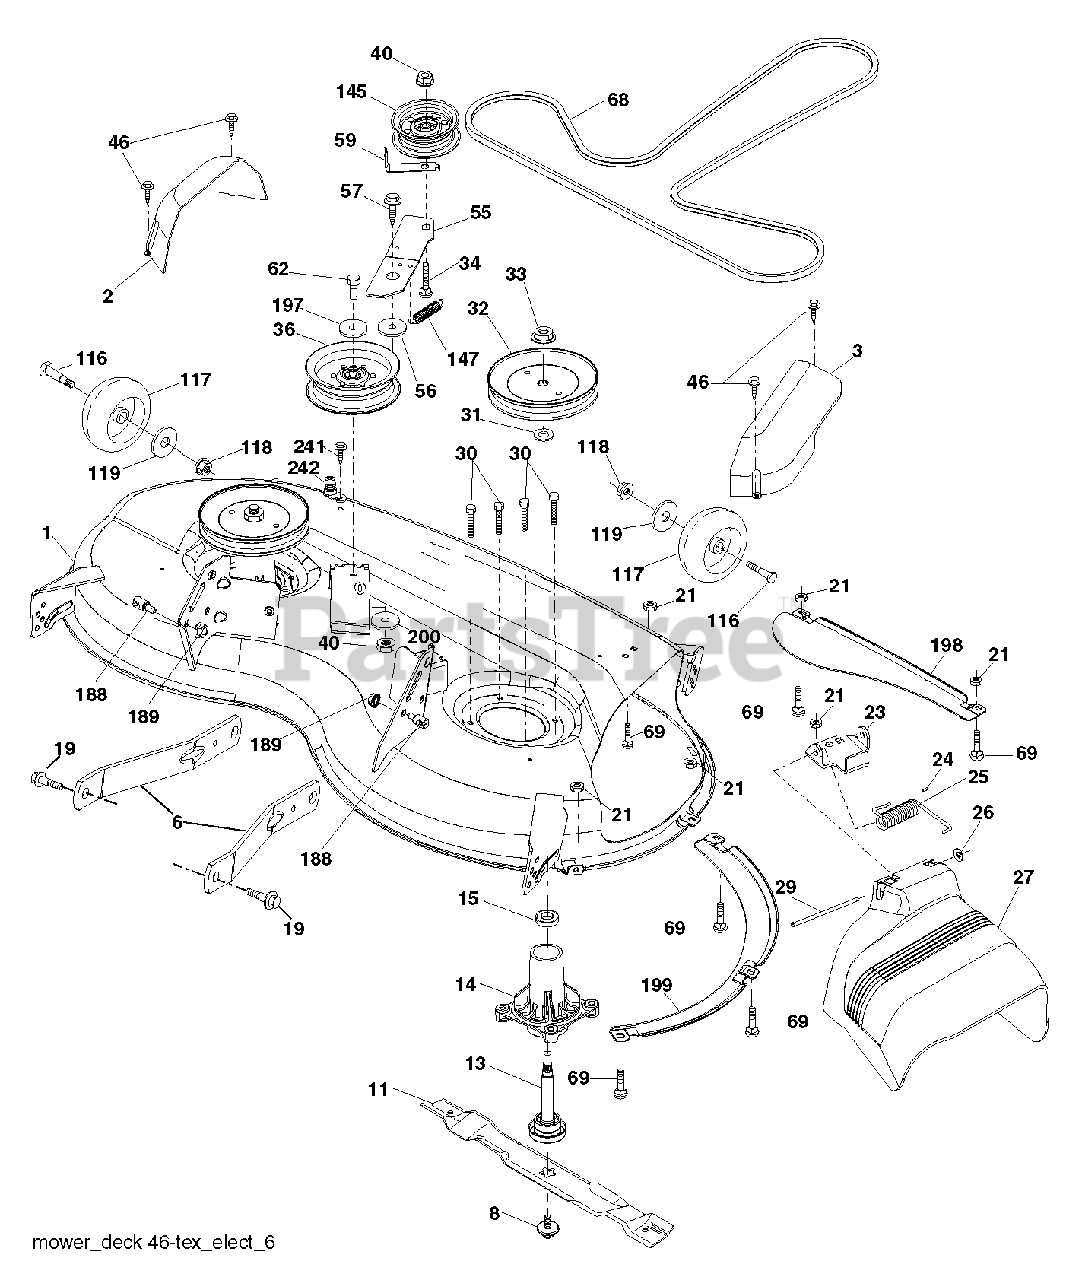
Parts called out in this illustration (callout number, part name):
1	DECK.WLDMT.WTUBES.46.4GWB.ORNG
2	COVER.MANDREL.LH.46"
3	COVER.MANDREL.RH.46"
6	ARM.SUSPENSION.MOWER.R
8	BOLT.WASHER.ASM.7/16-2
11	BLADE.MOWER.46".HI.LIFT
13	SHAFT.ASM.MDRL.N/GREASE.38
14	HOUSING.MANDREL.4PT.
19	BOLT.SHOULDER
21	LOCKNUT
23	BRKT.DEFLECTOR.38"2005+
24	CAP-SLEEVE LT
25	SPRING.TORSION.DEFLECT
26	NUT PUSH M
27	SHIELD.DEFLECTOR.MOWER.46"BLAC
29	ROD.HINGE
30	SCREW, WASHER HEAD
31	WASHER.SPACER.MANDREL
32	PULLEY.MANDREL.5.438.PD
33	NUT.FLANGE.LOCK.TOP
34	BOLT.3/8-16X1.50
36	PULLEY.IDLER.2006
40	NUT LOCK FLG 3/8-16 UNC
46	SCREW.1/4-20X5/8
56	SPACER.RETAINER
57	SCREW 3/8-16X1
59	GUARD, BELT
62	BOLT-HEX EAK
68	V-BELT
69	BOLT
116	BOLT.SHOULDER.3/8-16X3-5/8.
117	WHEEL. GUAGE RALLY
118	LOCKNUT
119	WASHER
145	PULLEY.IDLER.48"PRIMARY
147	SPRING.MOWER.DRIVE.ELECTRIC
188	STUD.FASTNER.W/ANTI-ROTATE
189	NUT LOCK HEX FLANGE 5/16-18
197	WASHER
198	BAFFLE CENTER FRONT
199	BAFFLE FRONT RH
200	WASHER.13/32 X 1 X 1/2.11GUARD
241	SCREW.TT.#10-32X.5.3/8.FLANGE
242	PORT.WASHOUT
